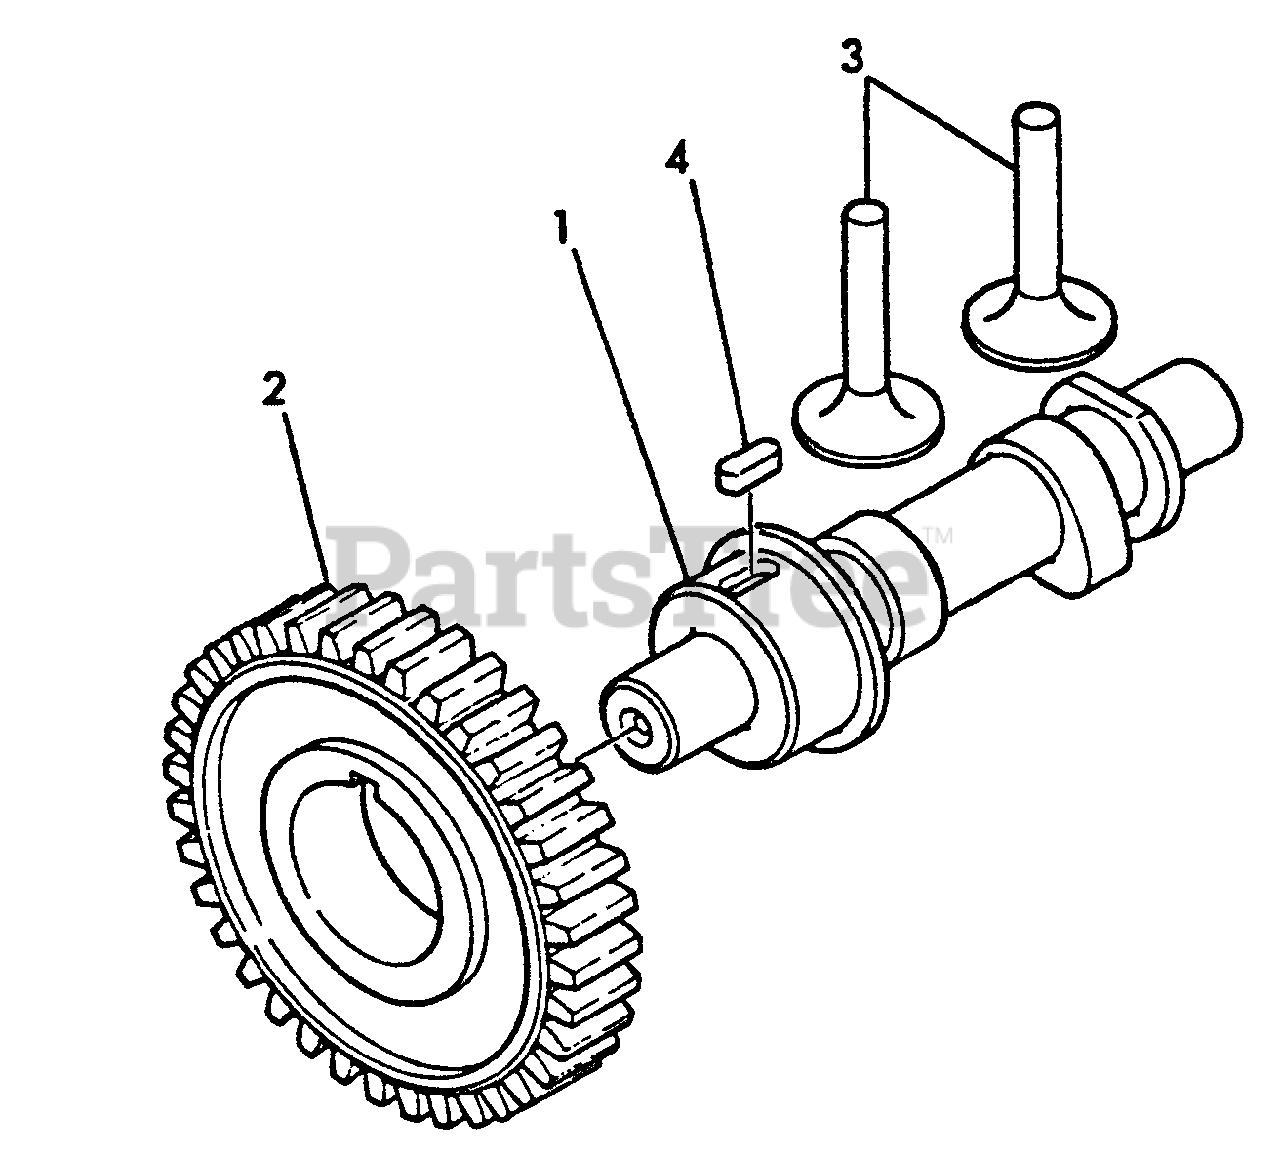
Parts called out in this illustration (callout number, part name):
1	CAMSHAFT
2	GEAR, CAMSHAFT
3	TAPPET
4	KEY - 4X10
